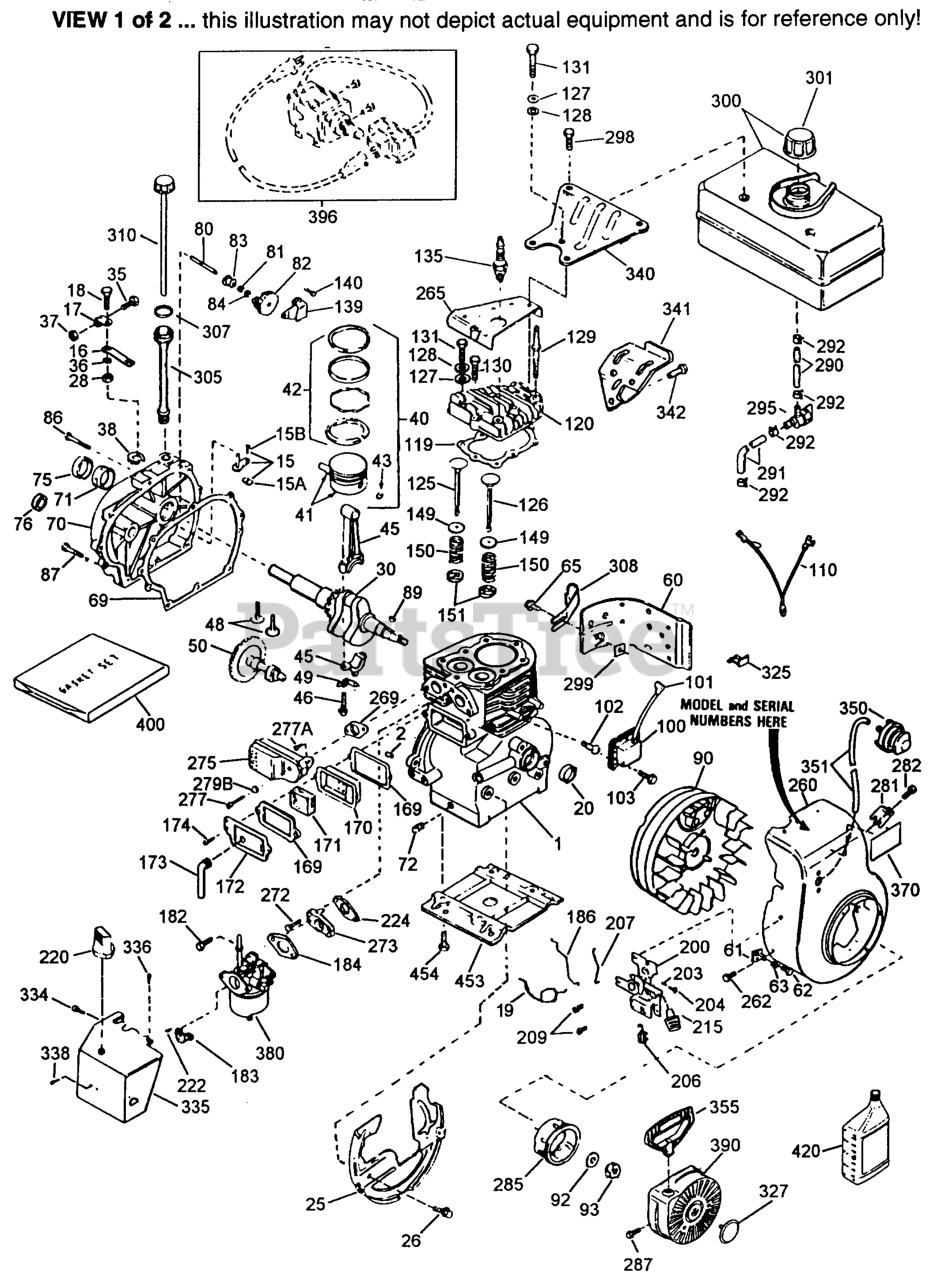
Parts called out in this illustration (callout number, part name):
1	CYLINDER
15	GOVERNOR ROD
15A	GOV YOKE
16	GOV LEVER
18	SCREW
20	OIL SEAL
25	BAFFLE
30	CRANKSHAFT
38	RET RING
40	PISTON ASSY 010
40	PISTON ASSY STD
40	PISTON ASSY 020
41	PISTON & PIN 20
41	PISTON & PIN 10
41	PISTON & PIN ST
42	RING SET STD
42	RING SET 010-NLA
42	RING SET 020
43	RET RING
45	CONN ROD--Discontinued
48	VALVE LIFTER
49	OIL DIPPER
50	CAMSHAFT
60	EXTENSION
61	BRACKET
63	GROMMET
70	CYL COVER
71	BUSHING
72	PIPE PLUG
75	OIL SEAL
80	GOV SHAFT
83	GOV SPOOL
84	RET RING
90	FLYWHEEL
100	LAMINATION
101	PLUG COVER
102	STUD
103	SCREW
110	GROUND WIRE
119	GASKET
120	GASKET
125	EXH VALVE STD
125	EXH VALVE OS
126	INT VALVE ST
126	INT VALVE OS
128	WASHER KIT
135	SPARK PLUG
139	BRACKET
140	SCREW
149	VALVE CAP
150	VALVE SPRING
151	VALVE CAP
170	BREATHER
171	ELEMENT
172	VALVE COVER
183	BRACKET
186	GOV LINK
200	CONTROL ASSY
203	COMP SPRING
204	SCREW
206	TERMINAL
222	SCREW
260	BLOWER HSG
265	COVER
269	GASKET
273	CARB FLANGE
275	MUFFLER
285	STARTER CUP
290	FUEL LINE
291	FUEL LINE
295	FUEL FITTING
300	FUEL TANK
301	FUEL CAP
305	FILLER TUBE
310	DIPSTICK
327	STARTER PLUG
335	CARB COVER
340	TANK BRACKET
341	TANK BRACKET
350	PRIMER
351	PRIMER LINE
355	START HANDLE
370	DECAL
370B	DECAL
370E	DECAL
380	CARBURETOR
390	STARTER
400	GASKET SET
408	SNOW SEAL
420	OIL SAE 5W30
453	ENGINE BASE
